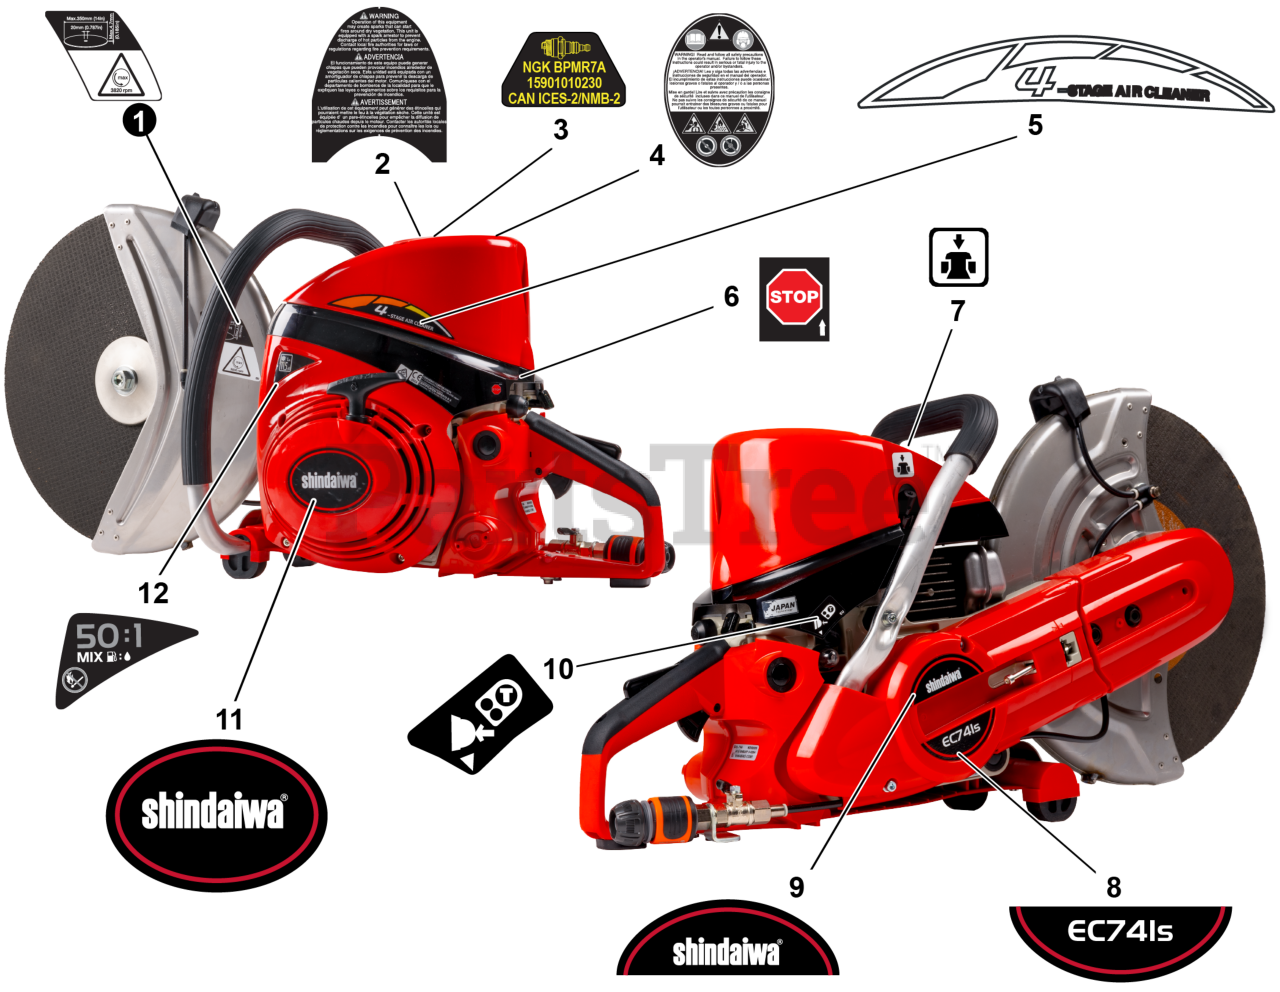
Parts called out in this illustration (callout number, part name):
1	LABEL - CAUTION
2	LABEL - CAUTION
3	LABEL - SPARK PLUG - BPMR7A
4	LABEL - CAUTION
5	LABEL - AIR FILTER
6	LABEL - STOP
7	LABEL - DECOMPRESSION
8	LABEL - MODEL - EC741S
9	LABEL - SHINDAIWA
10	LABEL - PURGE PUMP
11	LABEL - SHINDAIWA
